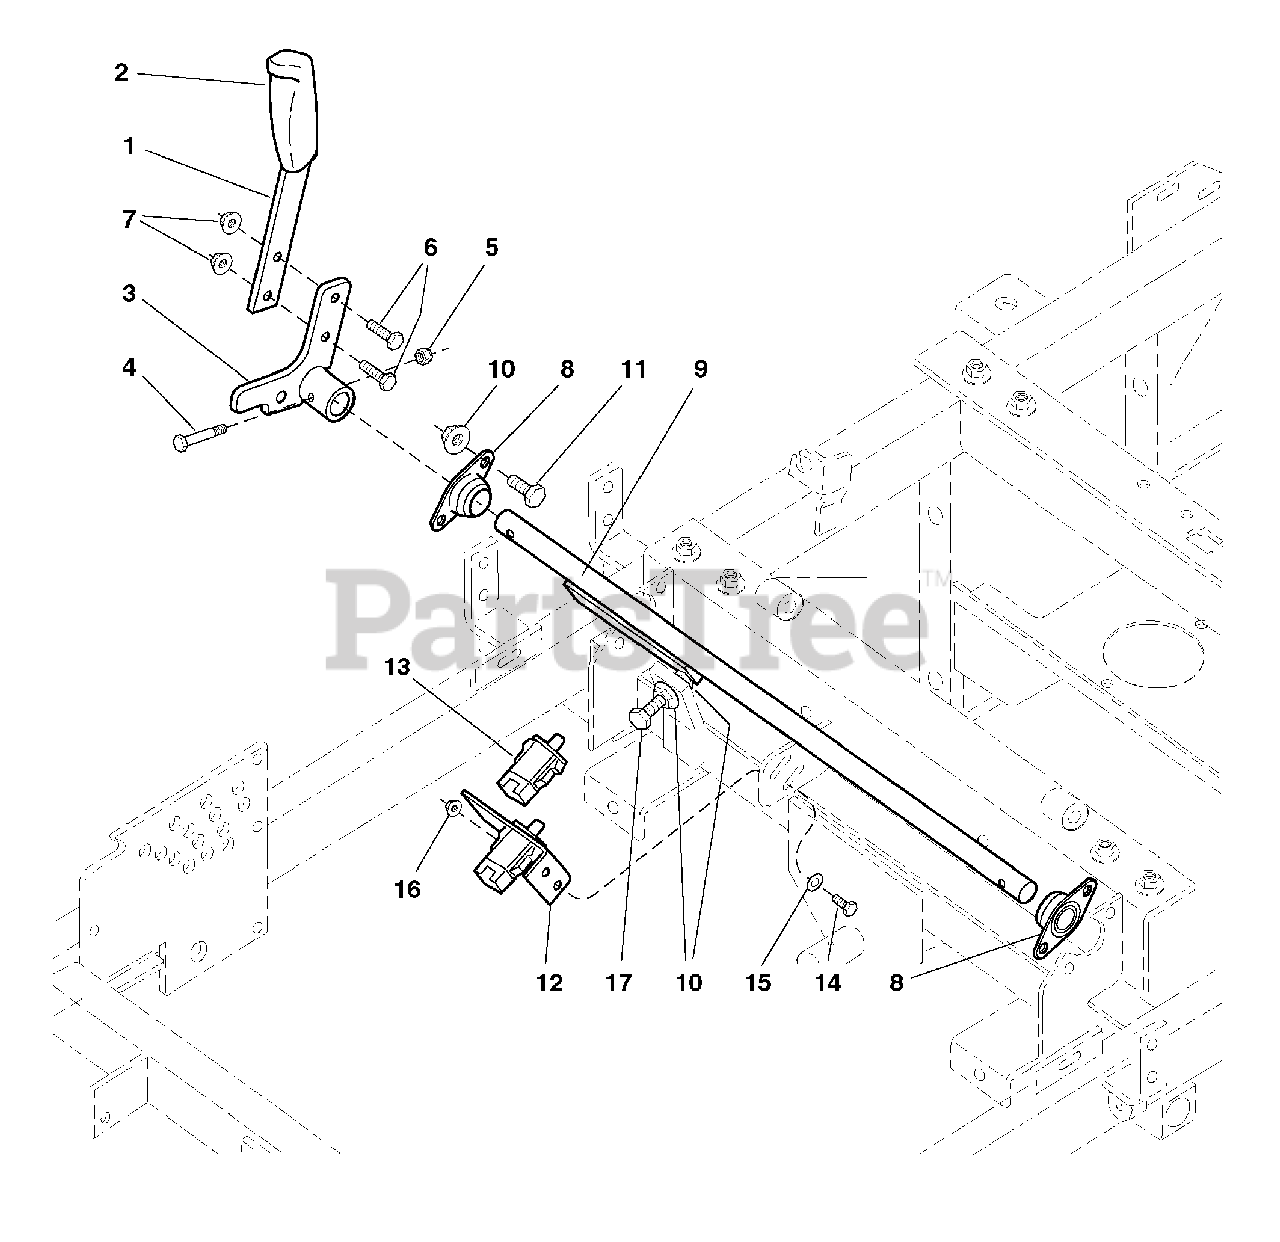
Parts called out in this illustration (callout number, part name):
1	BRAKE HANDLE
3	BRAKE HANDLE MOUNT
4	CAPSCREW, Hex Hd, 1/4-20 x 1-3/4
5	NUT, Hex, Nylon Lock, 1/4-20
6	CAPSCREW, Hex Hd, 5/16-18 x 1
7	NUT, Hex, Serrated Flange, 5/16-18
8	BEARING, Flange
9	BRAKE HANDLE SHAFT
10	NUT, Hex, Serrated Flange, 3/8-16
11	CAPSCREW, Hex Hd, 3/8-16 x 3/4
12	SWITCH MOUNT BRACKET
13	SWITCH, DP NO/NC SNAP-IN
14	CAPSCREW, Hex Hd, 1/4-20 x 3/4
15	WASHER, 1/4 SAE (5025154)
16	NUT, Hex, Serrated Flange, 1/4-20
17	CAPSCREW, Hex Hd, TFL, 3/8-16 x 1-3/4
